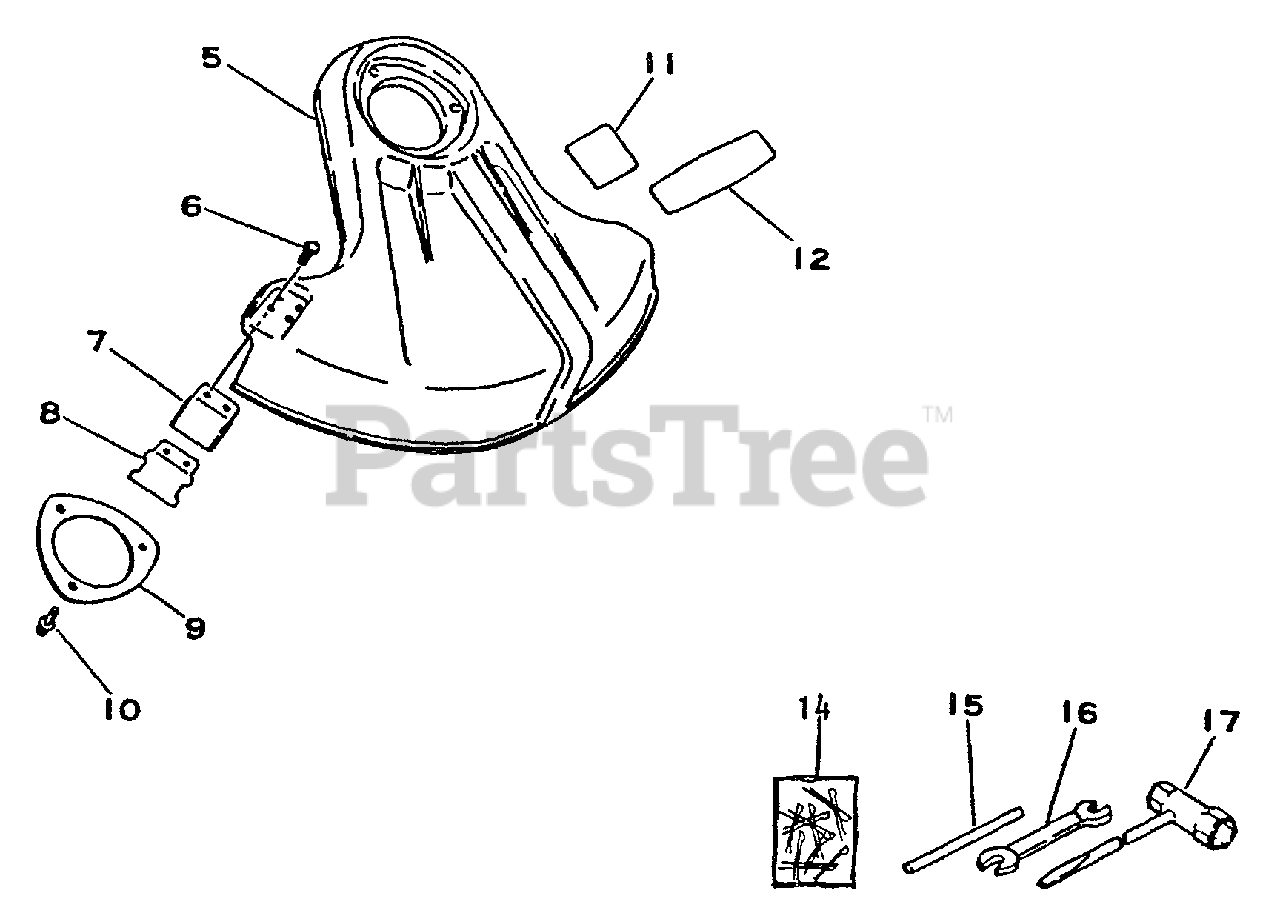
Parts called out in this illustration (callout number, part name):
5	SHIELD, DEBRIS - PLASTIC
6	SCREW - 5X16
7	KNIFE, TRIMMER LINE
8	GUARD
9	PLATE, SHIELD
10	SCREW - 5X16
11	LABEL - CAUTION
12	LABEL - ECHO
14	PIN, SPLIT - 2X22
15	LOCKING TOOL
16	SPANNER - 8X10mm
17	T-WRENCH - 17X19mm
